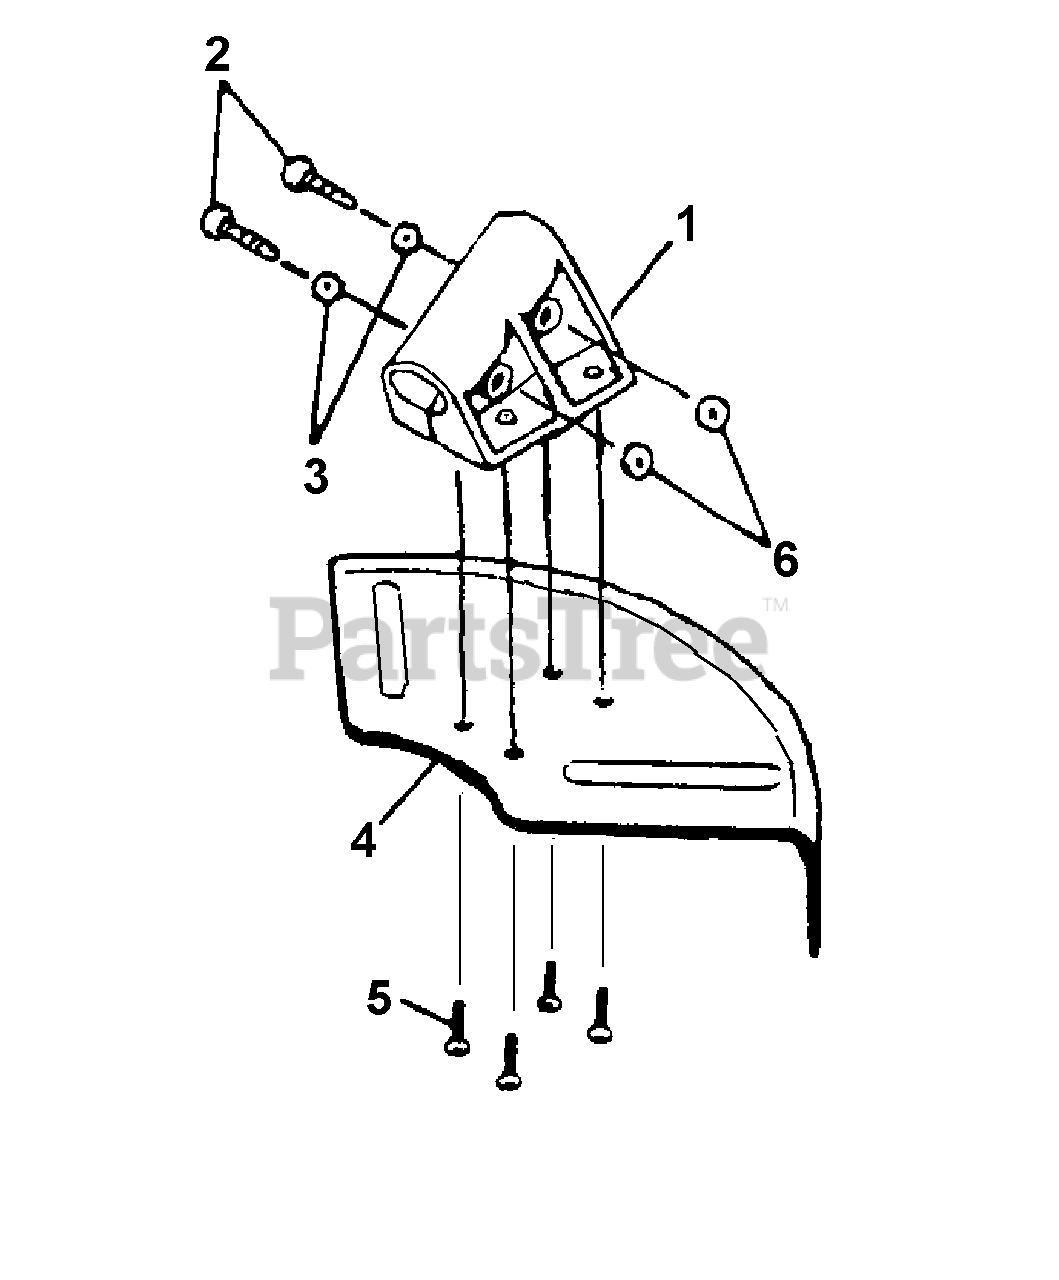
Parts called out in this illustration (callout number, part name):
1	Bracket, Blade Guard
2	Screw
3	Washer
4	Guard
5	Screw
